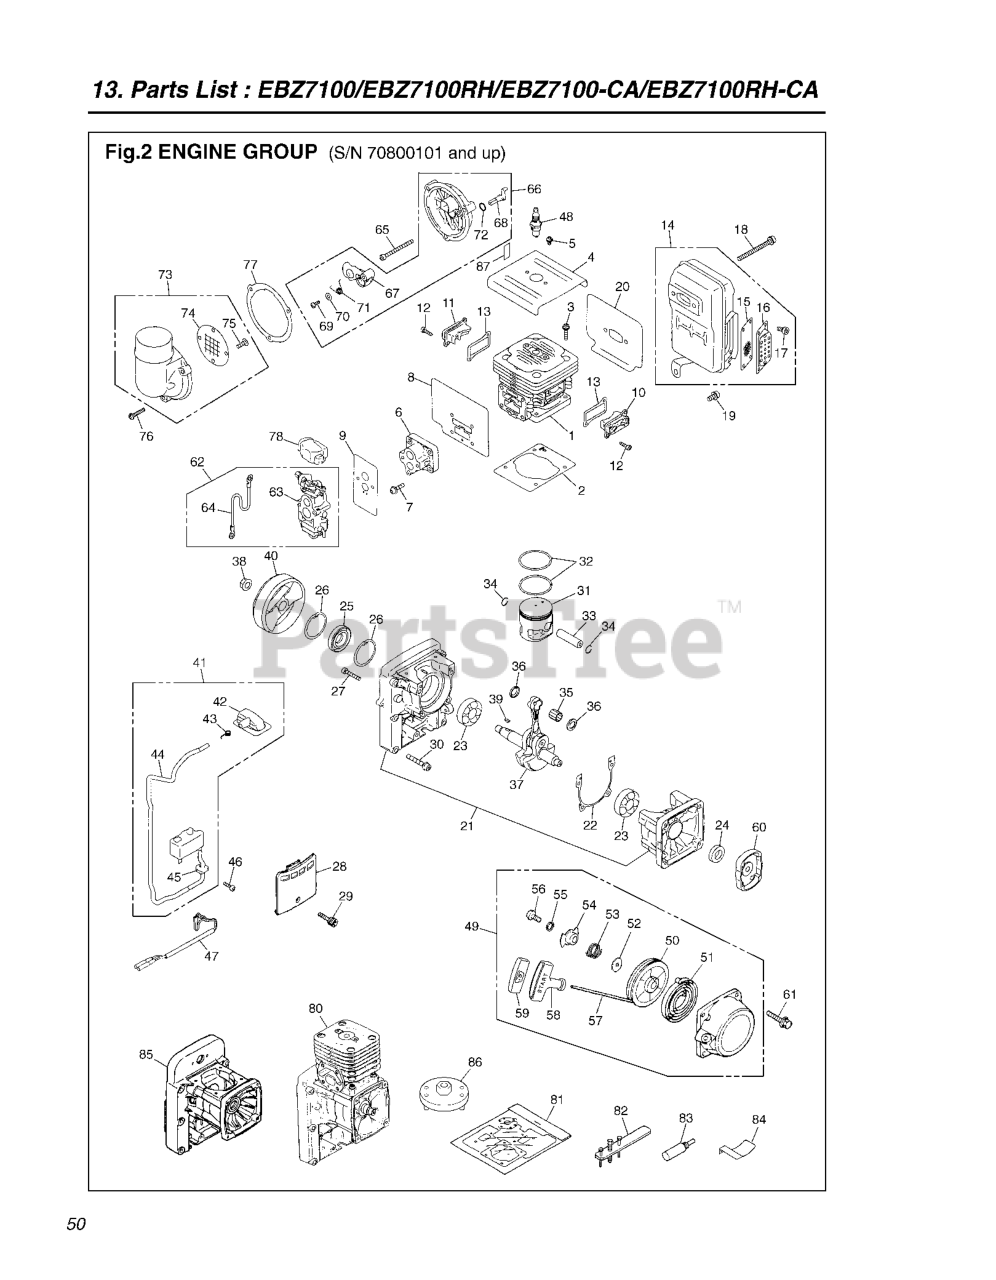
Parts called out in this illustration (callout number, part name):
1	CYLINDER
2	GASKET
3	BOLT
4	PLATE
6	INSULATOR
8	GASKET
10	COVER,TR-S
11	COVER,TR-F
14	MUFFLER ASSY
15	%ARRESTER
16	DIFFUSER
21	CRANKCASE-C
22	GASKET
23	BALL BEARING
24	SEAL
25	SEAL
26	SNAP-RING
28	COVER
30	BOLT
31	PISTON***
34	SNAP RING
35	ROLLER BEARING
37	SHAFT COMP
39	KEY
40	ROTOR
41	COIL ASSY
43	SPRING
44	RP TUBE-A
45	GROMMET
47	CORD-COMP
48	PLUG CMR7H
49	RECOIL ASSY
50	REEL
52	WASHER
53	SPRING FRICTION
54	PLATE
57	ROPE
58	KNOB
59	COVER
60	PULLEY ASSY
62	CARBURETOR SET
63	CARBURETOR ASSY
64	CORD
67	CHOKE PLATE
69	SCREW
70	RP_WASHER
73	CUP COVER ASSY
74	SCREEN
80	SHORT BLOCK
81	GASKET KIT
82	PULLER ASSY
85	RP_CRANKCASE-A
86	RP_PULLER
87	LABEL,CHOKE
